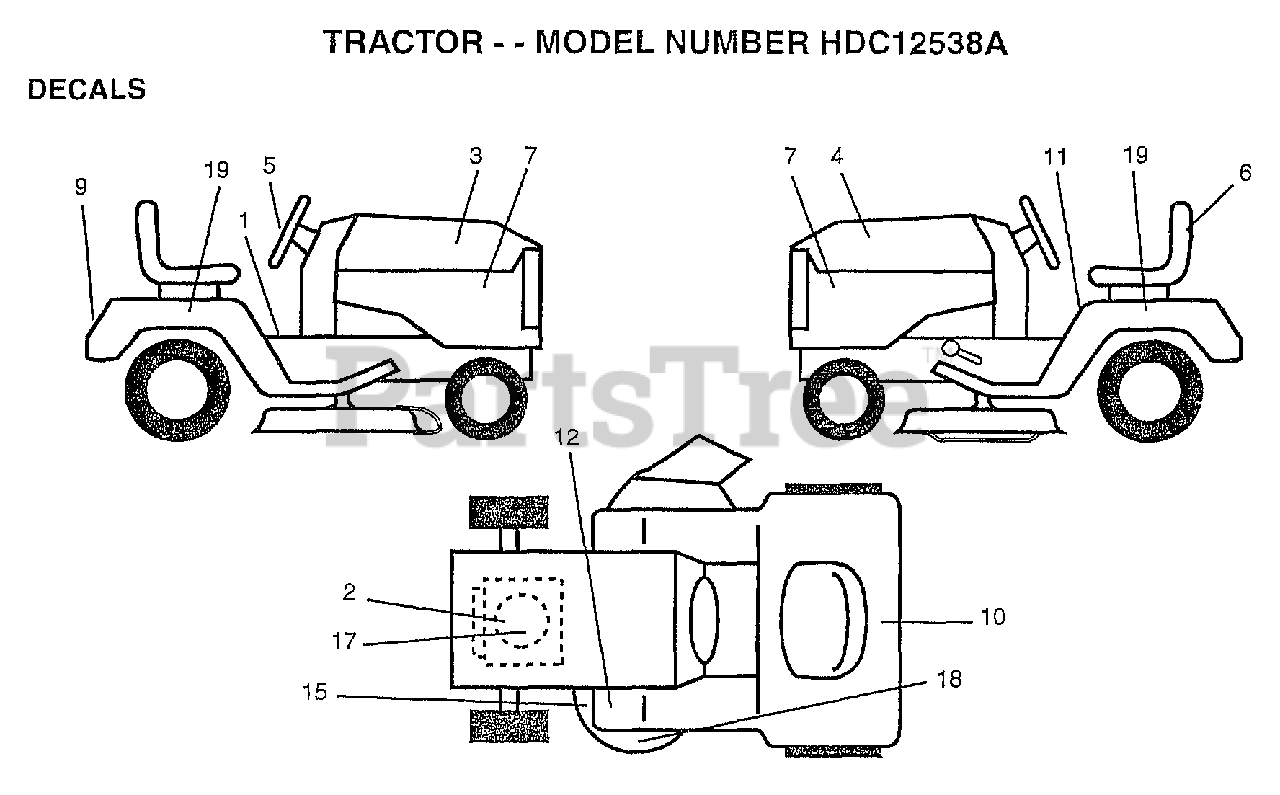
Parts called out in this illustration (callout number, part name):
2	DECAL, HP ENGINE
3	"DECAL HOOD,RH"
4	DECAL HOOD LH
5	"DECAL INS,STRG WH"
6	"DECAL SEAT,REPLCM"
7	"DECAL PENL,SIDE"
9	DECAL-FENDER
10	DECAL.BATRY.3-3908
11	"DECAL FENDER,DANG"
12	DECAL CLUT/BRAKE
15	DECAL
17	"DECAL ENGINE,REPL"
18	"DECAL MOWER,HOME"
19	"DECAL FENDER,5 SP"
